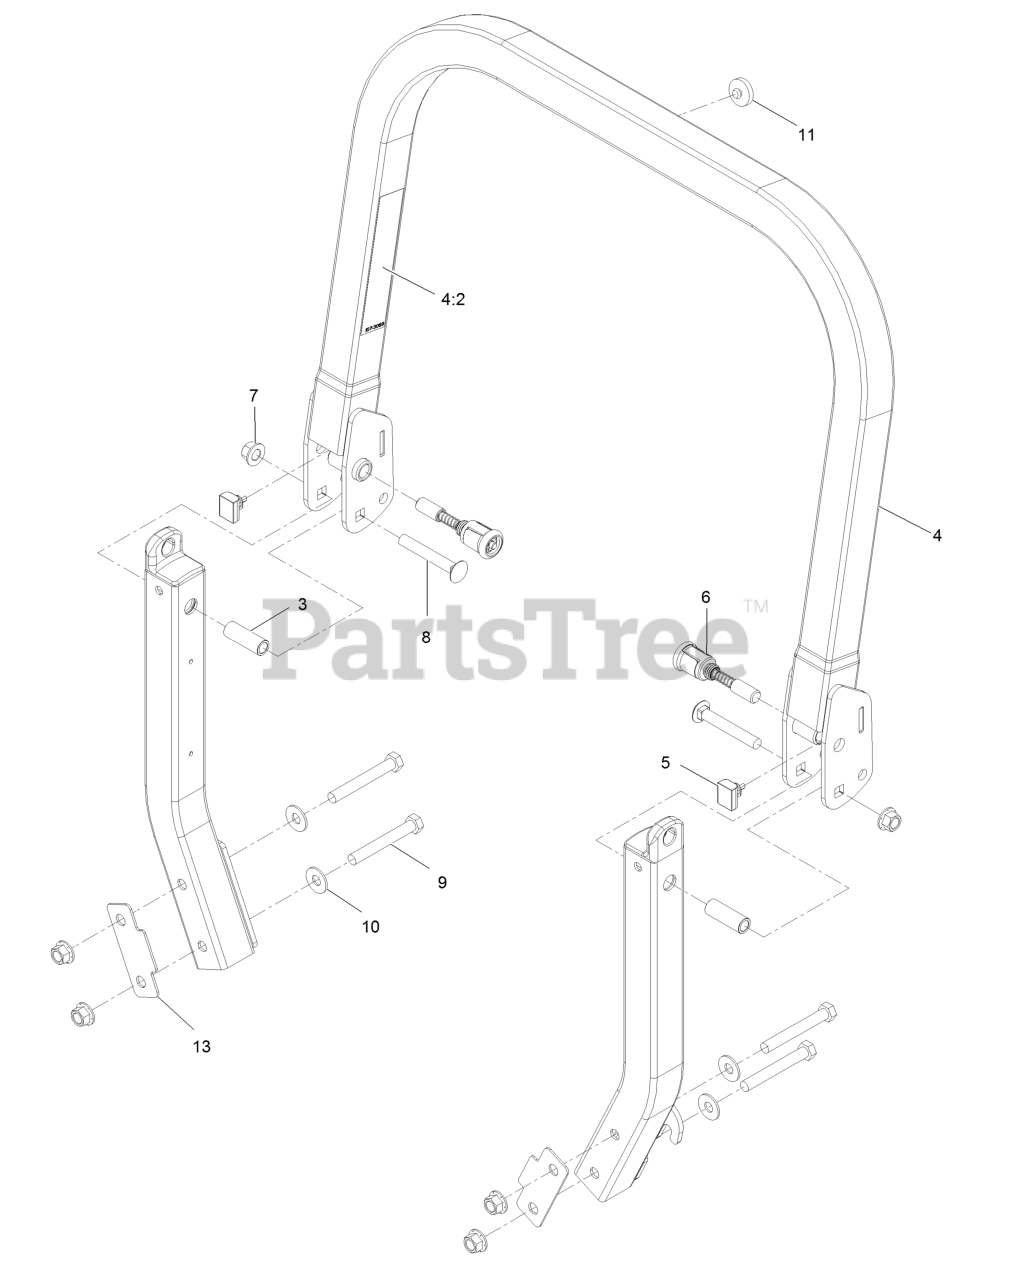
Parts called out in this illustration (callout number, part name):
4	Upper ROPS ASM
4:2	Decal-Warning
5	Bumper-ROPS
6	Pin-Spring
7	Nut-Lock 1/2-13
8	Bolt-Carriage 1/2-13 X 3 1/2
9	Screw-HH
10	Washer, Spring Disc 1/2
11	Bumper-Push-In, Rubber
